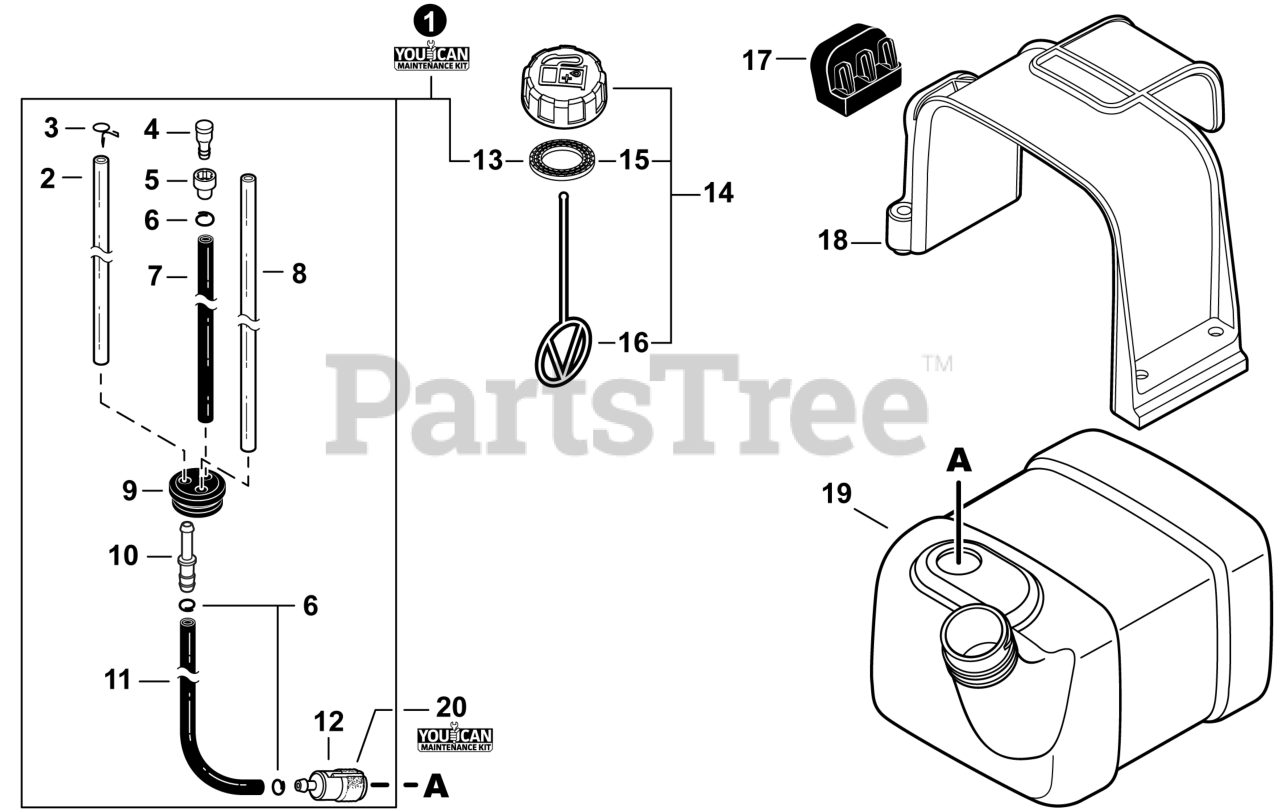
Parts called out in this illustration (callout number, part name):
1	FUEL SYSTEM KIT - YOUCAN
2	PIPE, FUEL 3.5x6x205 CLEAR
3	CLIP, SPRING 5.2
4	VENT ASSY
5	HOLDER, VENT
6	CLIP 6.5 MM
7	PIPE, FUEL 3x6x40 BLACK
8	PIPE, FUEL 3x6x180 YELLOW
9	GROMMET, FUEL
10	CONNECTOR, PIPE 5x3.5
11	PIPE, FUEL 3x6x120 BLACK
12	FILTER, FUEL
13	GASKET, FUEL CAP
14	CAP ASSY, FUEL
15	GASKET, FUEL CAP
16	CONNECTOR, CAP L= 100 MM
17	CUSHION
18	RETAINER, FUEL TANK
19	TANK, FUEL
20	TUNE-UP KIT - YOUCAN?
